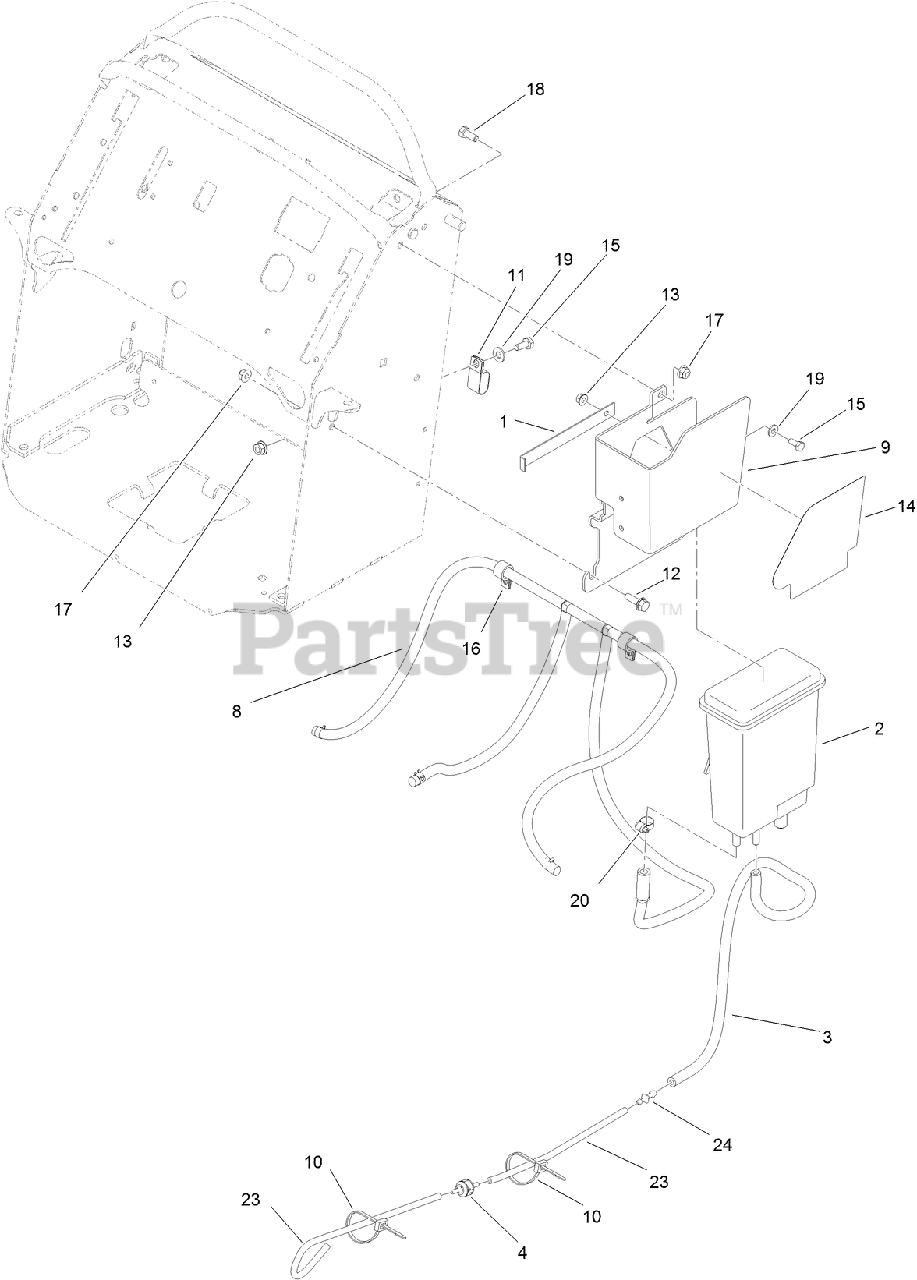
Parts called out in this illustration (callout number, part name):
1	PLATE-LOC
2	CANISTER-CARBON, 1200CC
3	HOSE-FUEL
4	VALVE-CHECK, VACUUM
8	VENT HOSE ASM
9	PLATE- ADAPTER
10	TIE-CABLE
11	CLAMP-TUBE, DOUBLE
12	SCREW-HHF
13	NUT-HHF
14	DECAL-SERVICE/SPARK ARREST
15	SCREW-HH
16	CLAMP-CABLE
17	NUT-HF, NI
18	SCREW-HH
19	WASHER-FLAT
20	CLAMP-WORM
23	HOSE-VENT, FORMED
24	FITTING-STRAIGHT
